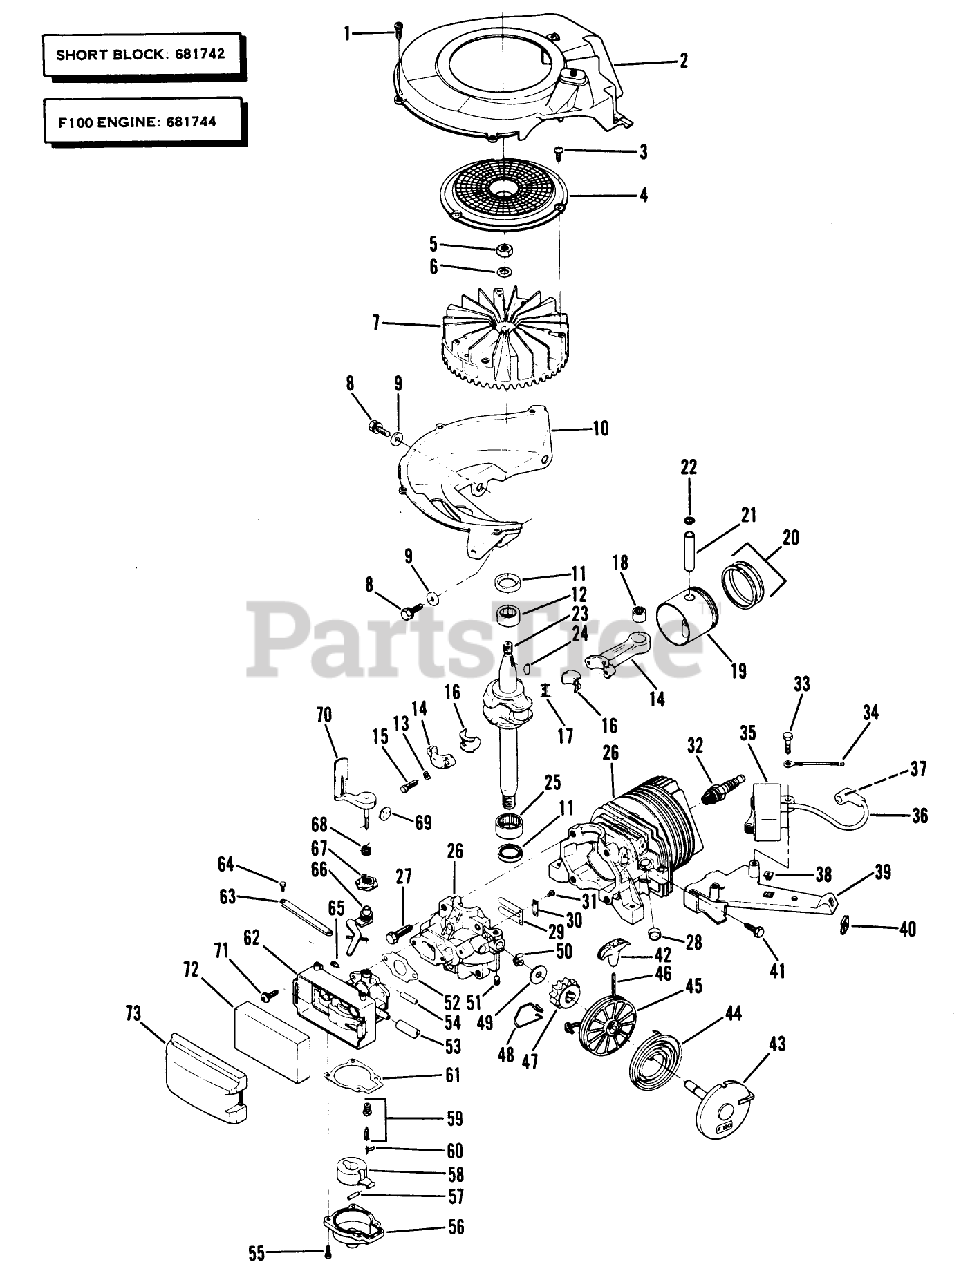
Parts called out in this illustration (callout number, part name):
2	AIR BAF&EYELET S
3	SCREW F
5	NUT
8	SCREW S
9	Washer
12	BEARING V
15	SCREW
16	LINER ASM
18	BEARING AY F
22	RING-RETAINING
24	KEY
25	BEARING V
27	SCREW S
28	PLUG-CORE VF
30	PLATE-BACKUP, REED
36	HT LEAD&COVER XEV
38	NUT-CLIP
40	NUT - SPEED S
42	HANDLE STARTER S
44	SPRING S
48	SPRING F
49	WASHER S
51	SET SCREW
52	GASKET CARB S
54	TUBING PRIMER S
55	SCREW-HH
65	F-SCREW CARB
66	LEVER
67	ADJUSTMENT COLLAR
68	SPRING
69	DISC S
71	SCREW
